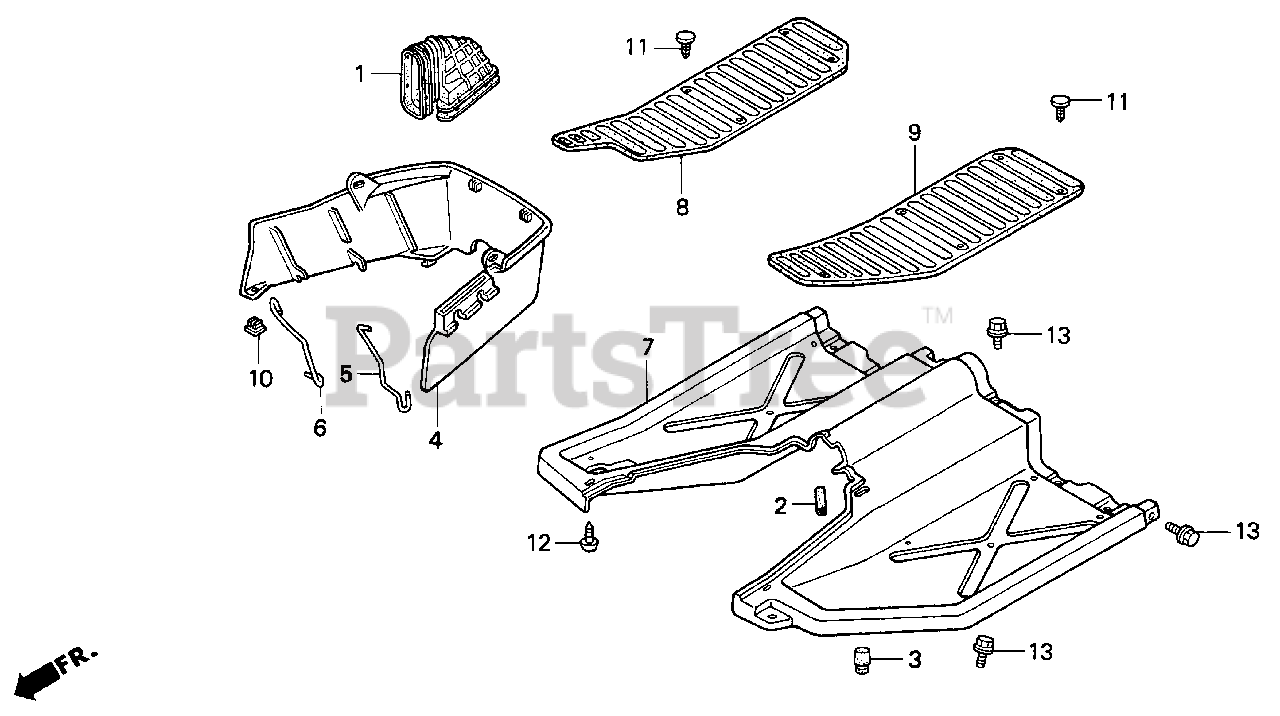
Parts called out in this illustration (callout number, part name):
2	PROTECTOR, HARNESS
3	RUBBER A, STOPPER
4	SHELL, COMPARTMENT *R165* (JOLLY RED)
5	ROD, COMPARTMENT SHELL
6	ROD, R. COMPARTMENT SHELL
7	PANEL, FLOOR *R165* (JOLLY RED)
8	FLOOR MAT, R.
9	FLOOR MAT, L.
10	GROMMET, SCREW (6MM)
11	CLIP, TRIM (5MM) *NH1L* (BLACK)
12	SCREW, TAPPING (5X16)
13	BOLT, FLANGE (6X12)
